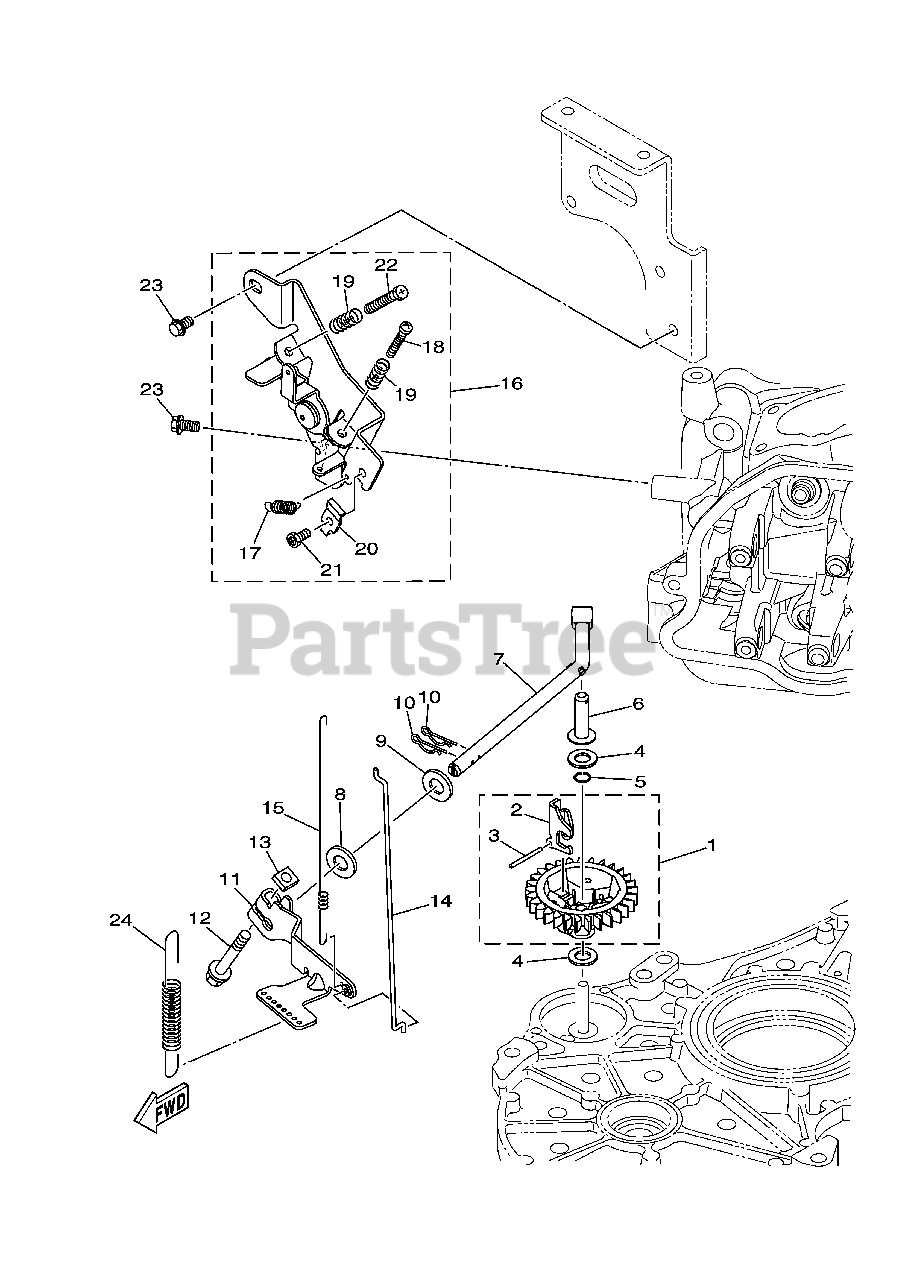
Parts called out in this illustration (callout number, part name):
1	FLYWEIGHT SHAFT ASSY
3	SHAFT, WEIGHT
4	WASHER, PLATE
7	FORK, GOVERNOR
8	WASHER, PLATE
9	WASHER, PLATE
11	GOVERNOR ASSY
12	BOLT, WITH WASHER
13	NUT, SQUARE
14	ROD, LINK
15	SPRING, TENSION
16	THROTTLE LEVER COMP.
17	SPRING, TENSION
18	SCREW, THROTTLE
19	SPRING, COMPRESSION
20	PLATE, ADJUST
21	SCREW, HEXAGON
22	SCREW, THROTTLE
23	BOLT, FLANGE
24	SPRING, GOVERNOR
